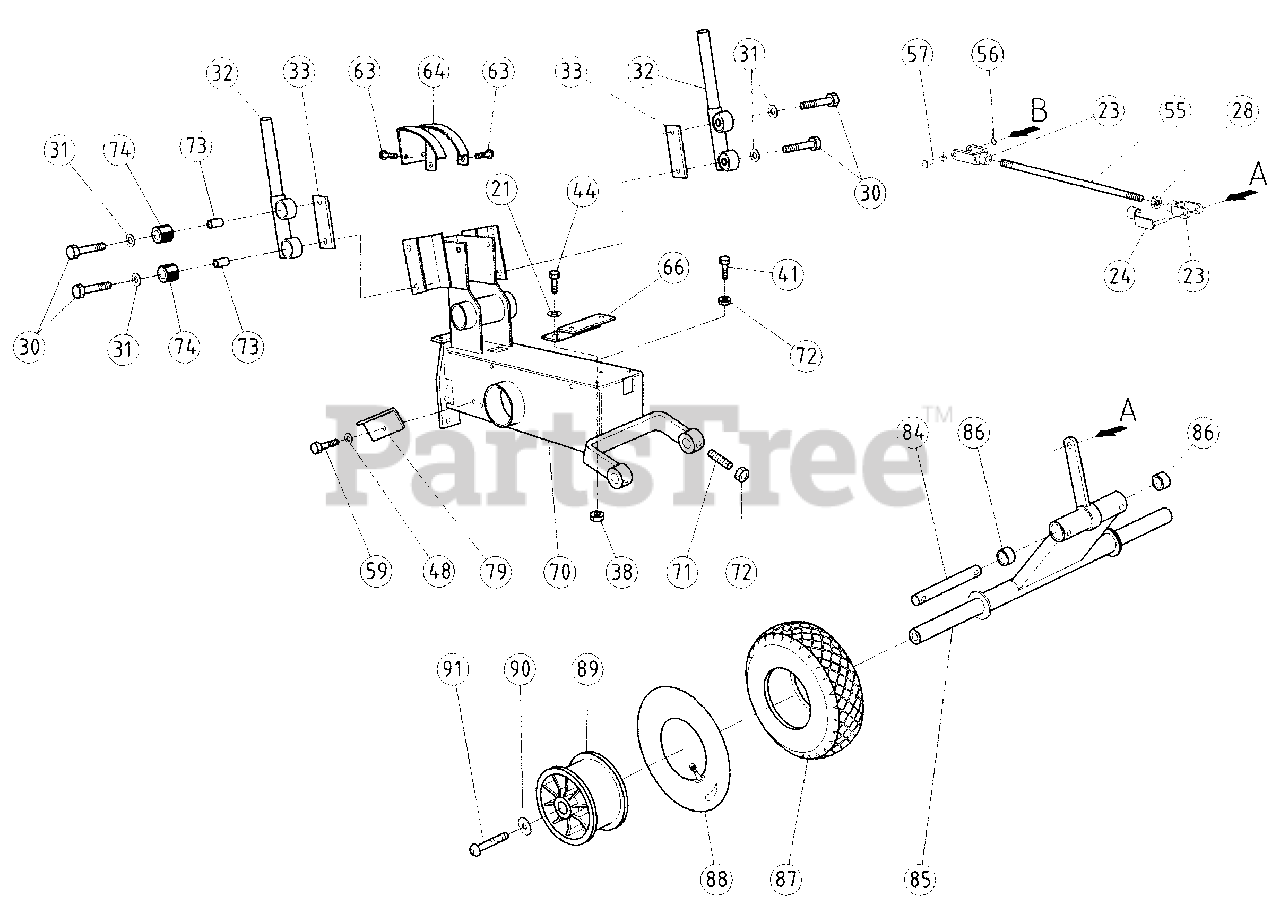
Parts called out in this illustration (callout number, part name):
21	Washer Flat M8
23	Fork 03216055
24	Clip Fork
30	Screwcap M10x50 P.F.
31	Washer wave M10
32	Support Handle
33	Nut Special for handle support
38	Nut Lock M8
41	Screwcap M8x25
44	Screwcap M8x20
48	Washer Flat M6
55	Connection tie-rod
56	Pin Roll M30x2.5
57	Pivot Ø 10
59	Screwcap M6x10
63	Screw Button Head M8x12
64	Quadrant Tooth Height
66	Support Front guard
70	Body Sod Cutter
71	Dowel M8x16
72	Nut 8 H 6.5
73	Dampener Vibration Internal Tube 12x10x28
74	Dampener Vibration Handle Support 30x12x28
79	Block Sliding Belt No. 1
84	Pivot Axle Front
85	Axle Front Complete
86	Bushing Self-Lubricating 16x20x22
87	Tire Front Wheel T090700
88	Tube Inner Front Wheel
89	Steel Rim Front wheel
90	Washer Flat M8x32
91	Screwcap M8x16
116	Retainer Cap
117	Roller Cage Bearing
